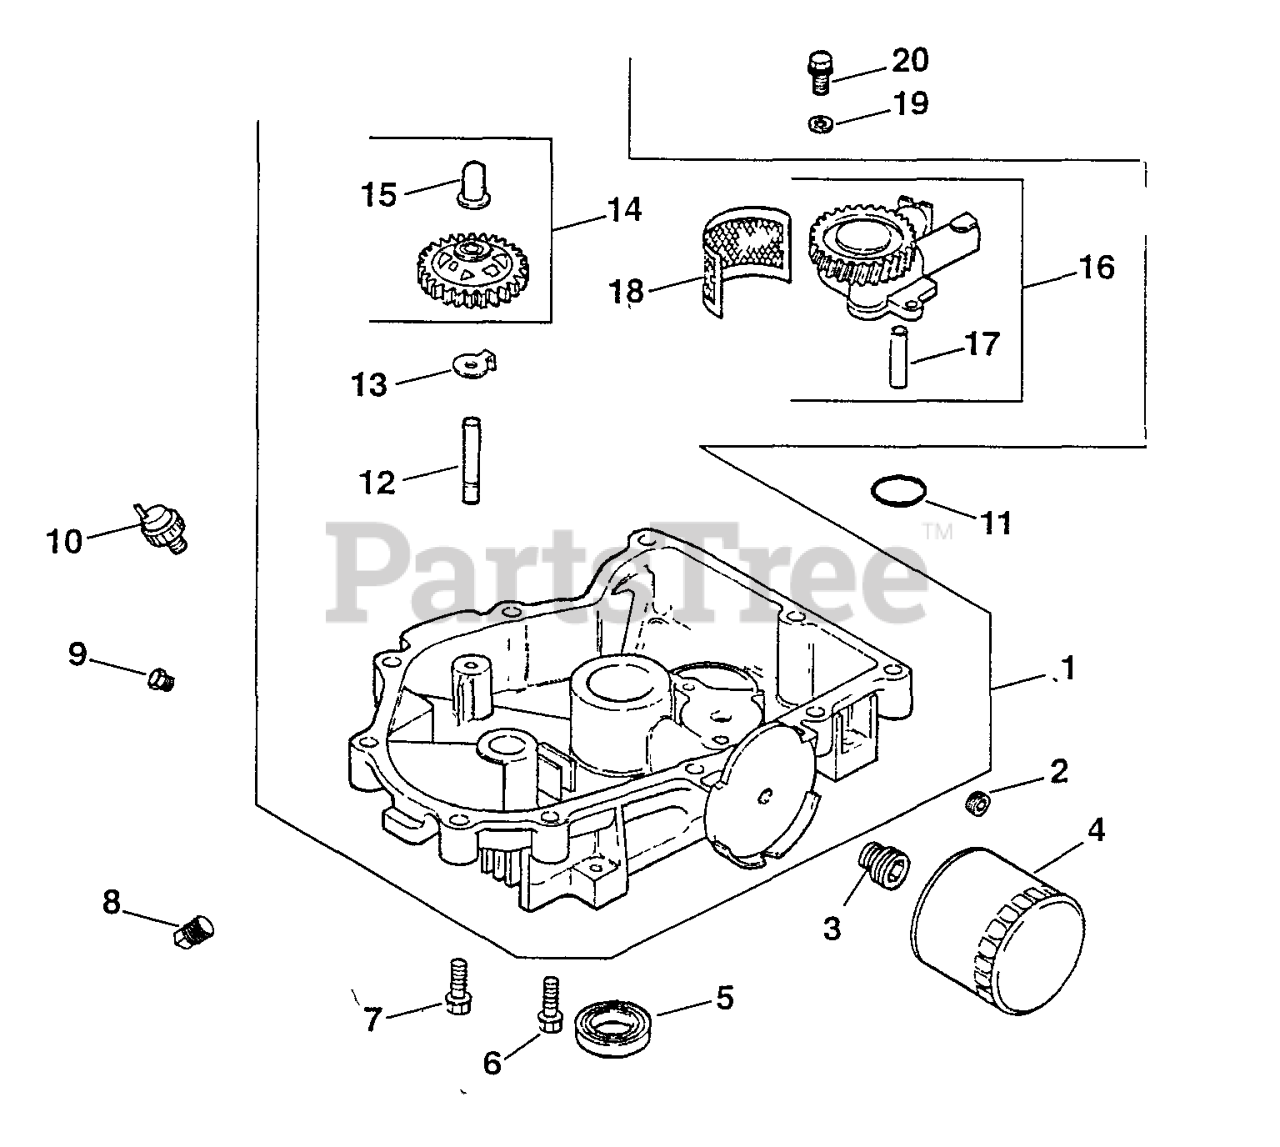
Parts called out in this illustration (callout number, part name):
1	PAN , OIL ASSEMBLY USE 24 199 32-S
2	PLUG, PIPE CTSK 3/8" USE 25 139 62-S
3	NIPPLE, OIL FILTER USE 24 136 09-S
4	FILTER, OIL
5	SEAL, OIL (KM)-USE 25 032 06-S
6	SCREW, FLG M8X1.25X45
7	SCREW, HEX FLANGE -USE 24 086 17-S
8	PLUG, SQ HD PIPE 3/8" USE 25 139 57-S
10	SWITCH, OIL PRESSURE
12	SHAFT, GOVERNOR GEAR
14	KIT, GOVERNOR GEAR W/PIN
15	PIN, GOVERNOR REGULATING
16	PUMP, OIL-DISCONTINUED
18	SCREEN - USE 25 162 07
19	WASHER - USE M-631005
20	SCREW - USE M-645025
